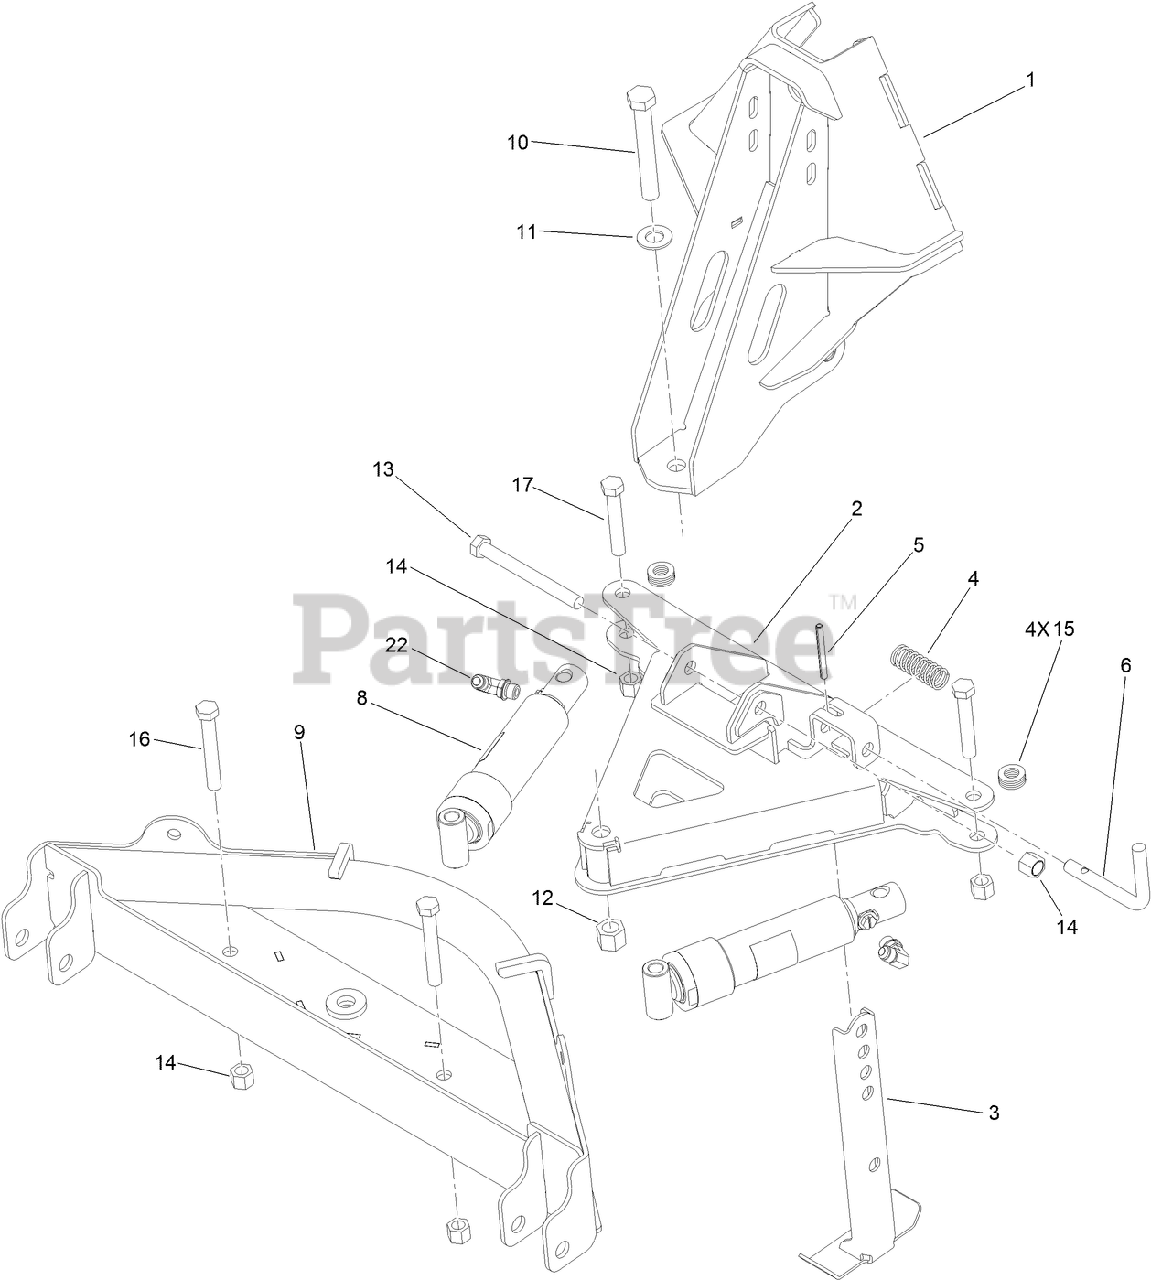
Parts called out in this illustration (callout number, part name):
1	COUPLER,FEMALE TRIANGLE,GRANDSTAND
2	PUSHFRAME ASM,STB,GRANDSTAND
3	KICKSTAND,GRANDSTAND
4	SPRING,.85OD X 2.25SS
5	PIN-ROLL, 1/4X2-1/2,YZN, KIT MSC03808
6	HANDLE,KKSTD,LD
8	CYLINDER-RAM
9	PUSHFRAME ATT BAR,STB,ATV/UTV
10	HHCS,5/8-11X4-1/2NC,GR5,YZN
11	WASHER,5/8 FLAT HARDEN YZN
12	NUT,5/8-11,NYL INS,YZN
13	HHCS,1/2-13X5,NC,GR5,YZN
14	NUT,1/2-13,NYL INS,YZN
15	WASHER,1/2,F436 HARD,F/W,YZN
16	HHCS,1/2-13X3-1/2,NC,GR5,YZN
17	HHCS,1/2-13X3,GR5,YZN
22	FITTING,90,6-MORB X 6-M37JIC
